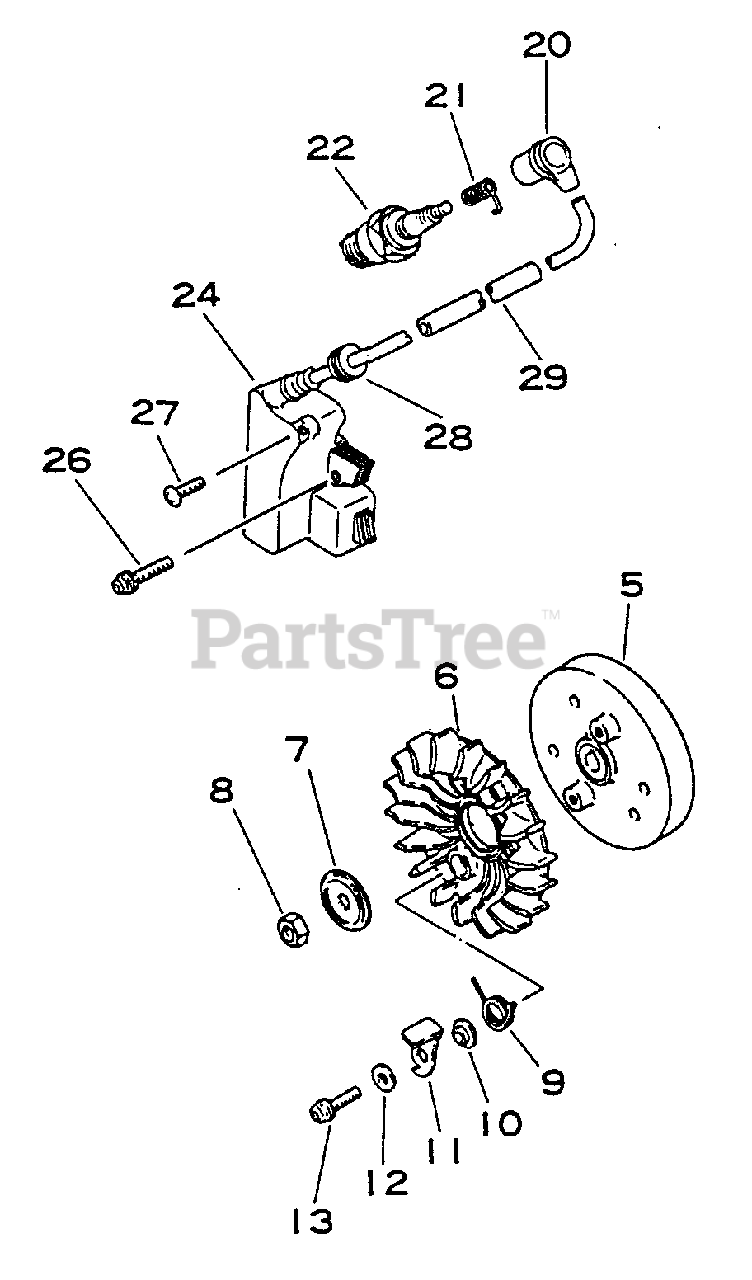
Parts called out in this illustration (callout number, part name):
5	FLYWHEEL
6	FAN
7	WASHER 8.2×31×0.8
9	SPRING, RETURN
10	SPACER, PAWL
11	PAWL, STARTER
12	WASHER 5.5×12×0.8
13	SCREW 5×14
20	CAP, SPARK PLUG
21	TERMINAL, SPARK PLUG
22	SPARK PLUG - CJ-6Y
24	COIL, IGNITION
26	BOLT 4×20
27	SCREW 4×8
